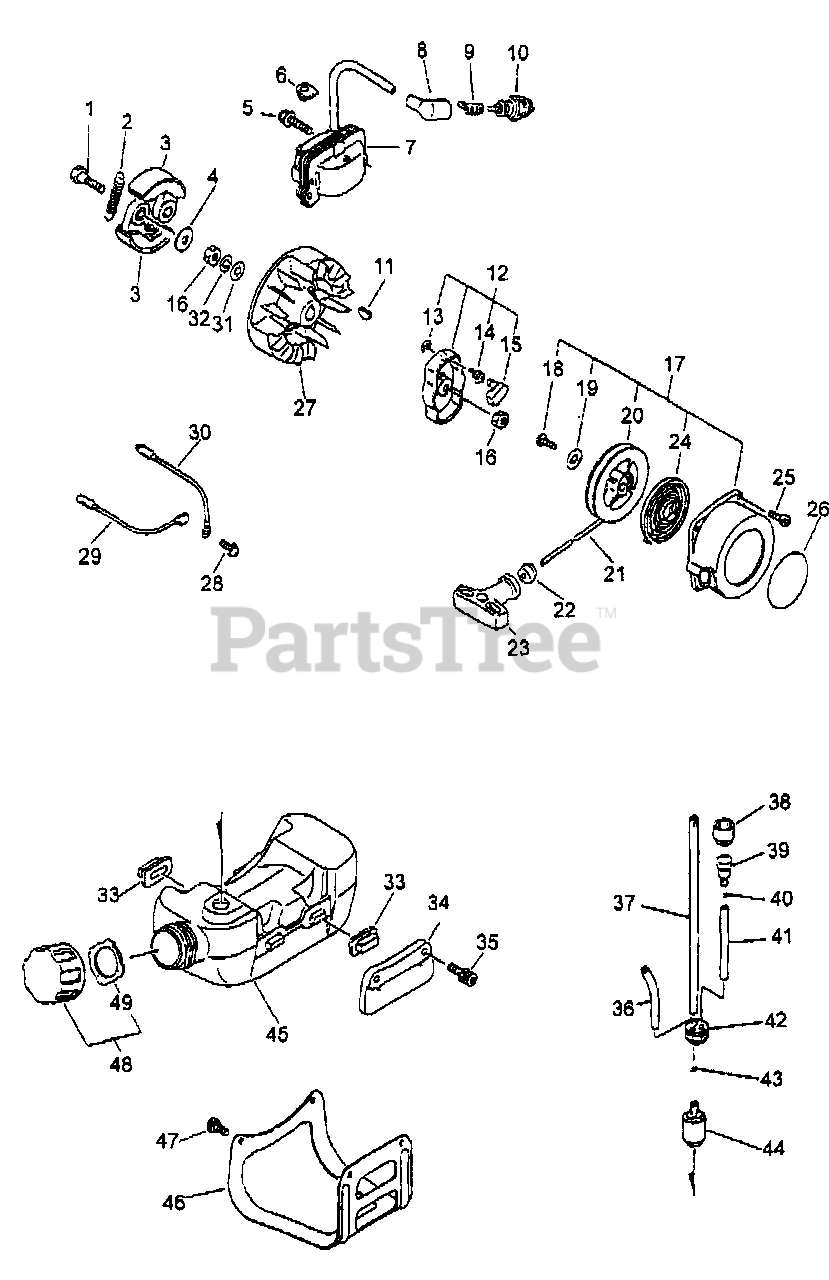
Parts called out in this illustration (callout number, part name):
1	BOLT, CLUTCH
2	SPRING, CLUTCH
3	SHOE, CLUTCH
4	WASHER - 6
5	SCREW - 5X20
7	COIL, IGNITION
8	CAP, SPARK PLUG
9	TERMINAL, SPARK PLUG CAP
10	SPARK PLUG -- BPM-7A
12	STARTER PAWL ASSY
13	RING, RETAINING - 4
14	SPRING, RETURN
15	PAWL, STARTER
17	STARTER ASSY
20	REEL, ROPE
21	ROPE, STARTER - 4X880
22	GUIDE, ROPE
23	GRIP, STARTER
24	SPRING, REWIND
25	SCREW - 4X14
26	LABEL - ECHO
27	FLYWHEEL
28	SCREW - 5X10
29	LEAD - IGNITION
30	LEAD - GROUND
31	WASHER - 8
32	LOCKWASHER - 8
33	CUSHION, FUEL TANK
34	BRACKET, FUEL TANK
35	SCREW - 5X20
36	PIPE - 3X6X90 -- CLEAR
37	PIPE - 3X5X180 -- BLACK
38	COVER, VENT
39	VENT, FUEL TANK
40	CLIP - 5.5
41	PIPE - 3X5X50 -- BLACK
42	GROMMET
43	CLIP - 6
44	FILTER, FUEL
45	TANK, FUEL
46	GUARD, FUEL TANK
47	SCREW - 5X12
48	CAP ASSY
49	GASKET, CAP
